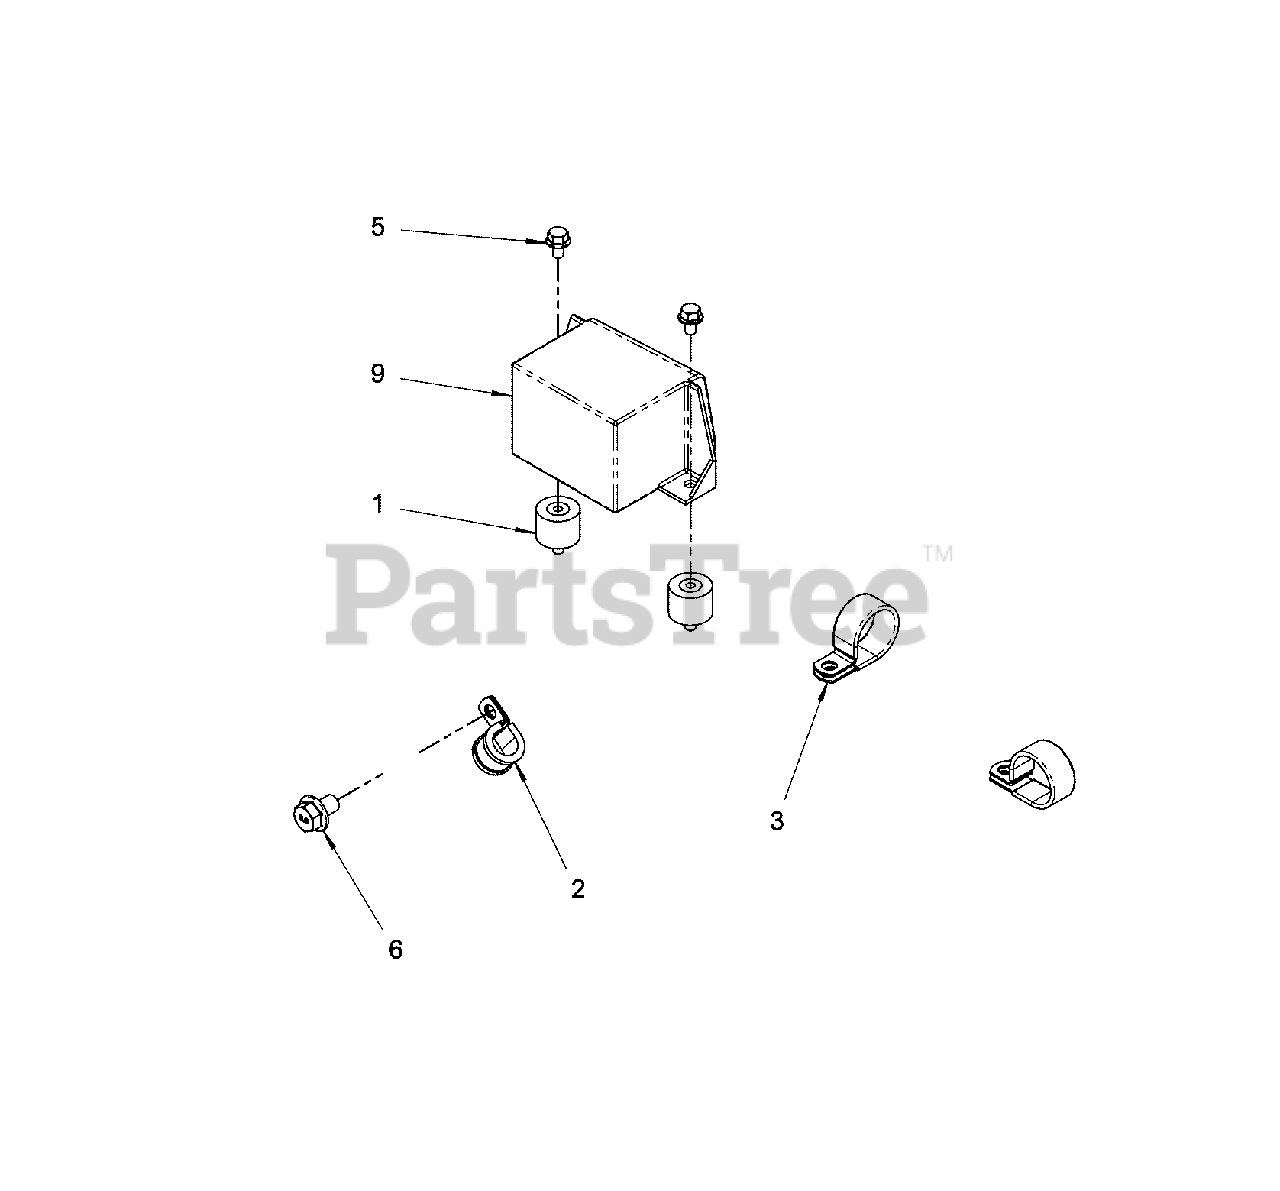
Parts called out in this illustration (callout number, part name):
1	* ISOLATOR
2	* CLAMP
3	* CLAMP
5	* BOLT
6	* BOLT
